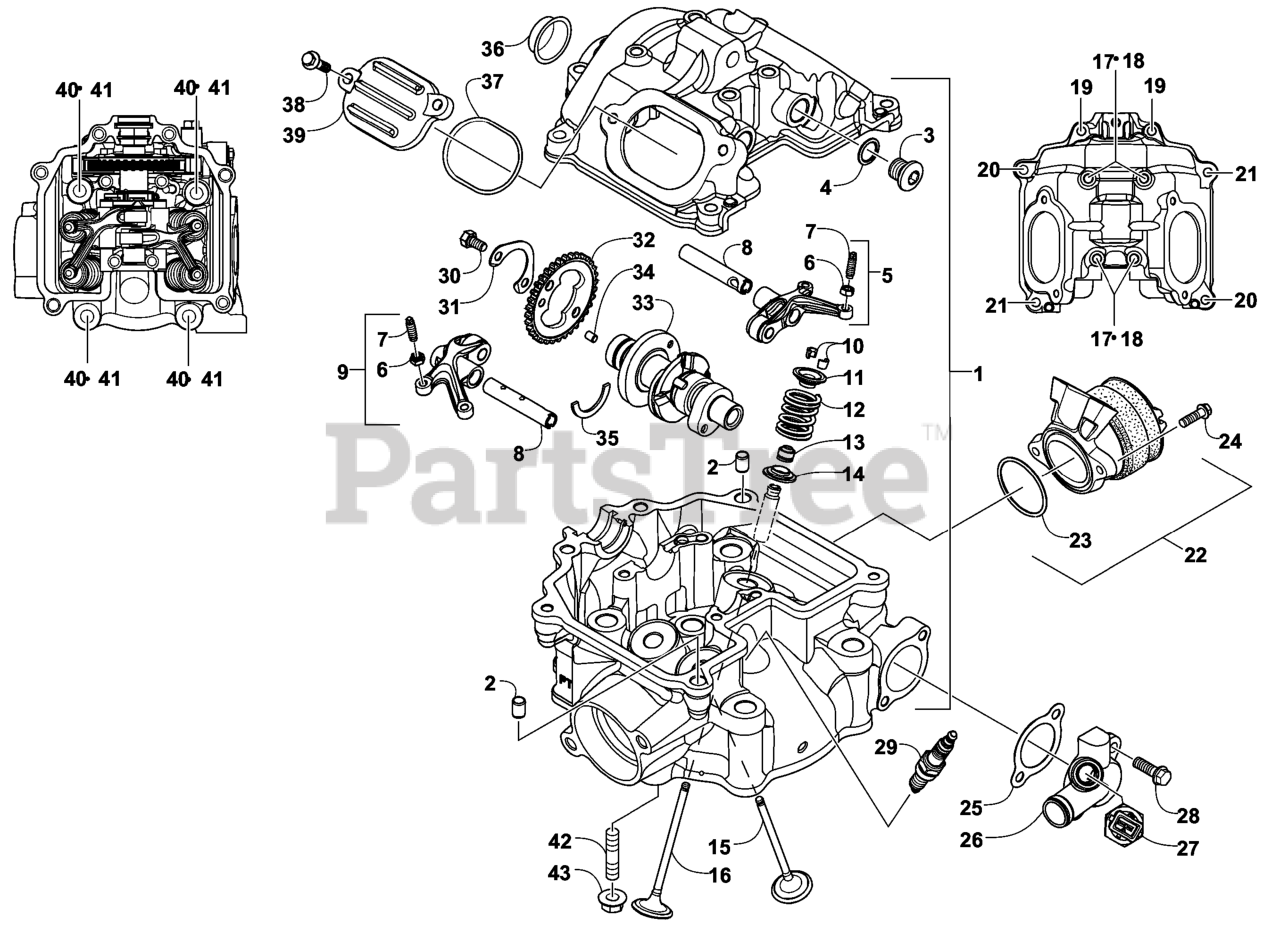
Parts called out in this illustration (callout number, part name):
1	HEAD-CYLINDER
2	PIN-DOWEL
3	PLUG-ROCKER ARM
4	WASHER-COMPRESSION
5	IN VALVE ROCKER ARM ASM
6	NUT-TAPPET, ADJUSTING
7	SCREW-TAPPET, ADJUSTING
8	SHAFT-IN ROCKER ARM
9	EXHAUST VALVE ROCKER ARM
10	COTTER-VALVE
11	RETAINER-SPRING
12	SPRING-VALVE, OUTER
13	SEAL-VALVE STEM
14	SEAT-VALVE SPRING
15	VALVE-EXHAUST
17	BOLT-FLANGE
18	SEAL-FASTENER
19	BOLT-FLANGE
21	BOLT-FLANGE
22	MANIFOLD-INTAKE
24	BOLT-FLANGE
25	GASKET-WATER COVER
26	HEAD-COVER, WATER
27	SENSOR-COOLANT TEMP (SYNE
28	BOLT-FLANGE
29	SPARK PLUG
30	BOLT-HEX
31	WASHER-LOCK
32	SPROCKET-CAMSHAFT
33	SHAFT-COMP CAM
34	DOWEL-ALIGNMENT
35	C-RING,CAMSHAFT
36	PLUG-HEAD
38	BOLT-FLANGE
39	CAP-INSPECTION COVER
40	BOLT-HFH
42	BOLT-STUD
43	NUT-HHF
